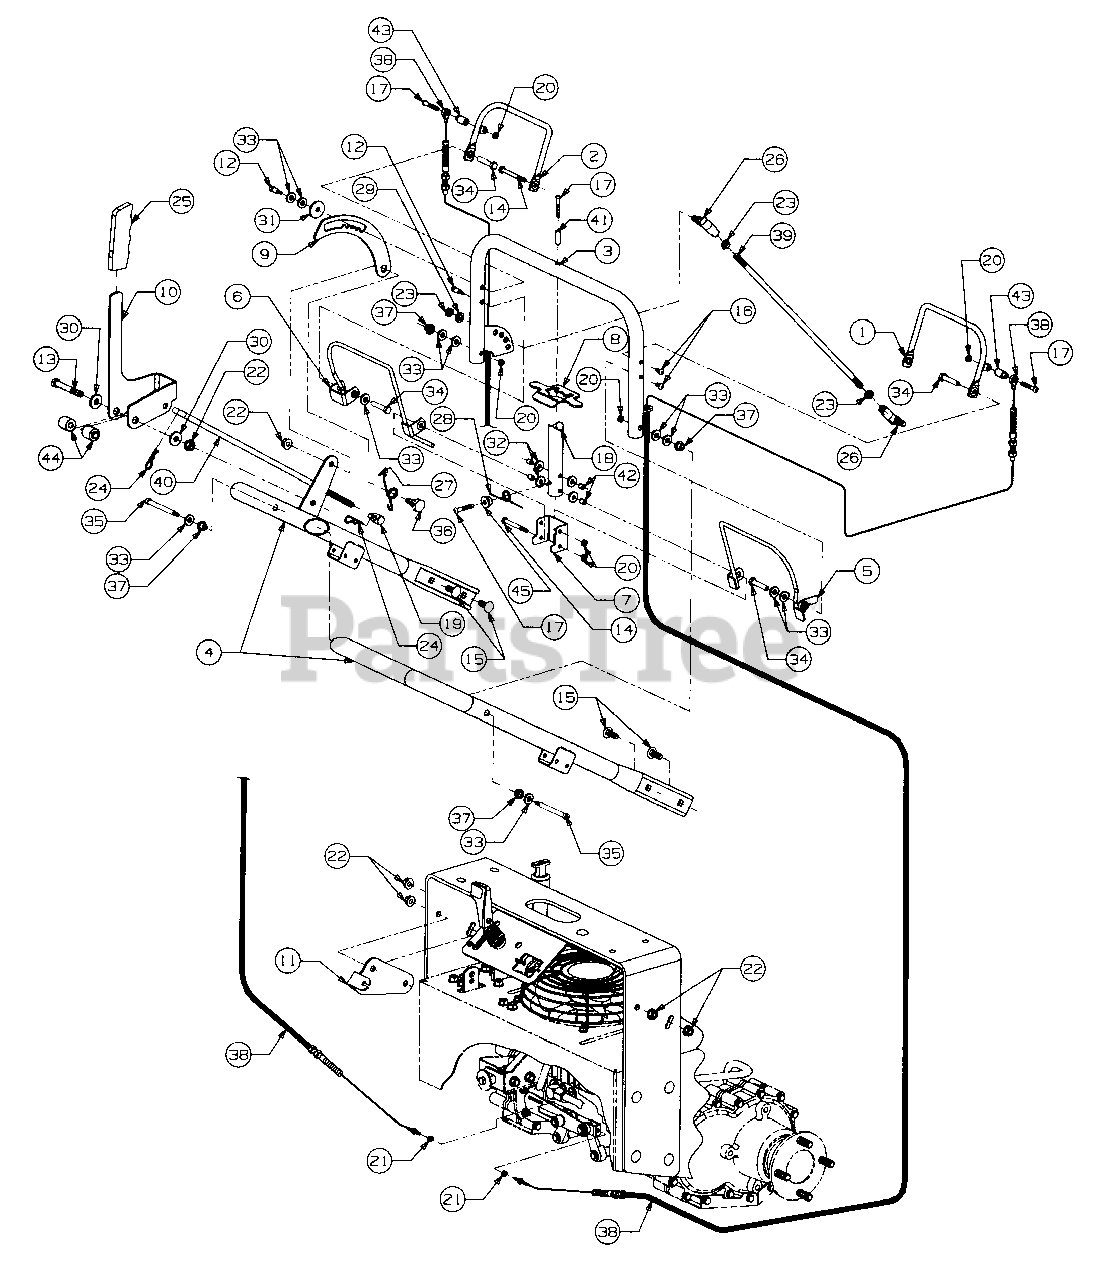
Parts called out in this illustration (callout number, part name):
1	Lever w/Bushings, R.H. Brake
2	Lever w/Bushings, L.H. Brake
3	Bar w/Graphics, Traction Control
4	Bar w/Graphic, LowerHandle
5	Lever w/Bushings, Operator-Present
6	Lever w/Bushings & Graphic, Speed Set
7	Stop, Handle
8	Latch w/Graphic, Park Brake
9	Plate, Speed Set
10	Handle, PTO Engagement
11	Bracket, Trans Release Cable Mtg
12	Screw, Socket Hd Shoulder
13	Screw, Hex Cap, 3/8-16 X 3.0 Lg GR8
14	Screw, Hex Cap, 1/4-20 X 2.50 Lg GR5
15	Bolt, Carriage, 3/8-16 X 1.0 Lg GR5
16	Screw, Button Hd, 1/4-20 X .50 Lg
17	Screw, Button Hd, 1/4-20 X 1 .50 Lg
18	Post, Park Brake
19	Ferrule, 3/8-24X .37 Dia
20	Nut, Hex Toplock, 1/4-20
21	Nut, Hex, #10-32
22	Nut, Hex Flanged Lock, 3/8-16
23	Nut, Hex Jam, 3/8-24 GR5
25	Grip, Engagement Handle
26	Ball Joint, 3/8-24
27	Spring, Torsion
28	Torsion, Spring
29	Washer, Lock, 3/8
30	Washer, Special .378 X 1.00 X .125 Thk
31	Washer, Flat, .32 X 1.25 X .06 Thk
32	Washer, Flat, .281 X .75 X .105 Thk
33	Washer, Flat, .321 X .75 X .119 Thk
34	Bolt, Shoulder
35	Bolt, Socket Hd Shoulder
36	Bolt, Stepped Shoulder
37	Bushing, Nylon
38	Cable, Brake Clutch
39	Rod, F/R Control
40	Rod, PTO Control
41	Spacer, 5/16 OD X 1/4 ID X .94 Lg
42	Spacer, 5/16 OD X 1/4 ID X .375 Lg
43	Spacer, Cable
44	Spacer, PTO Lower Pivot
45	Spacer, Spring Mtg
